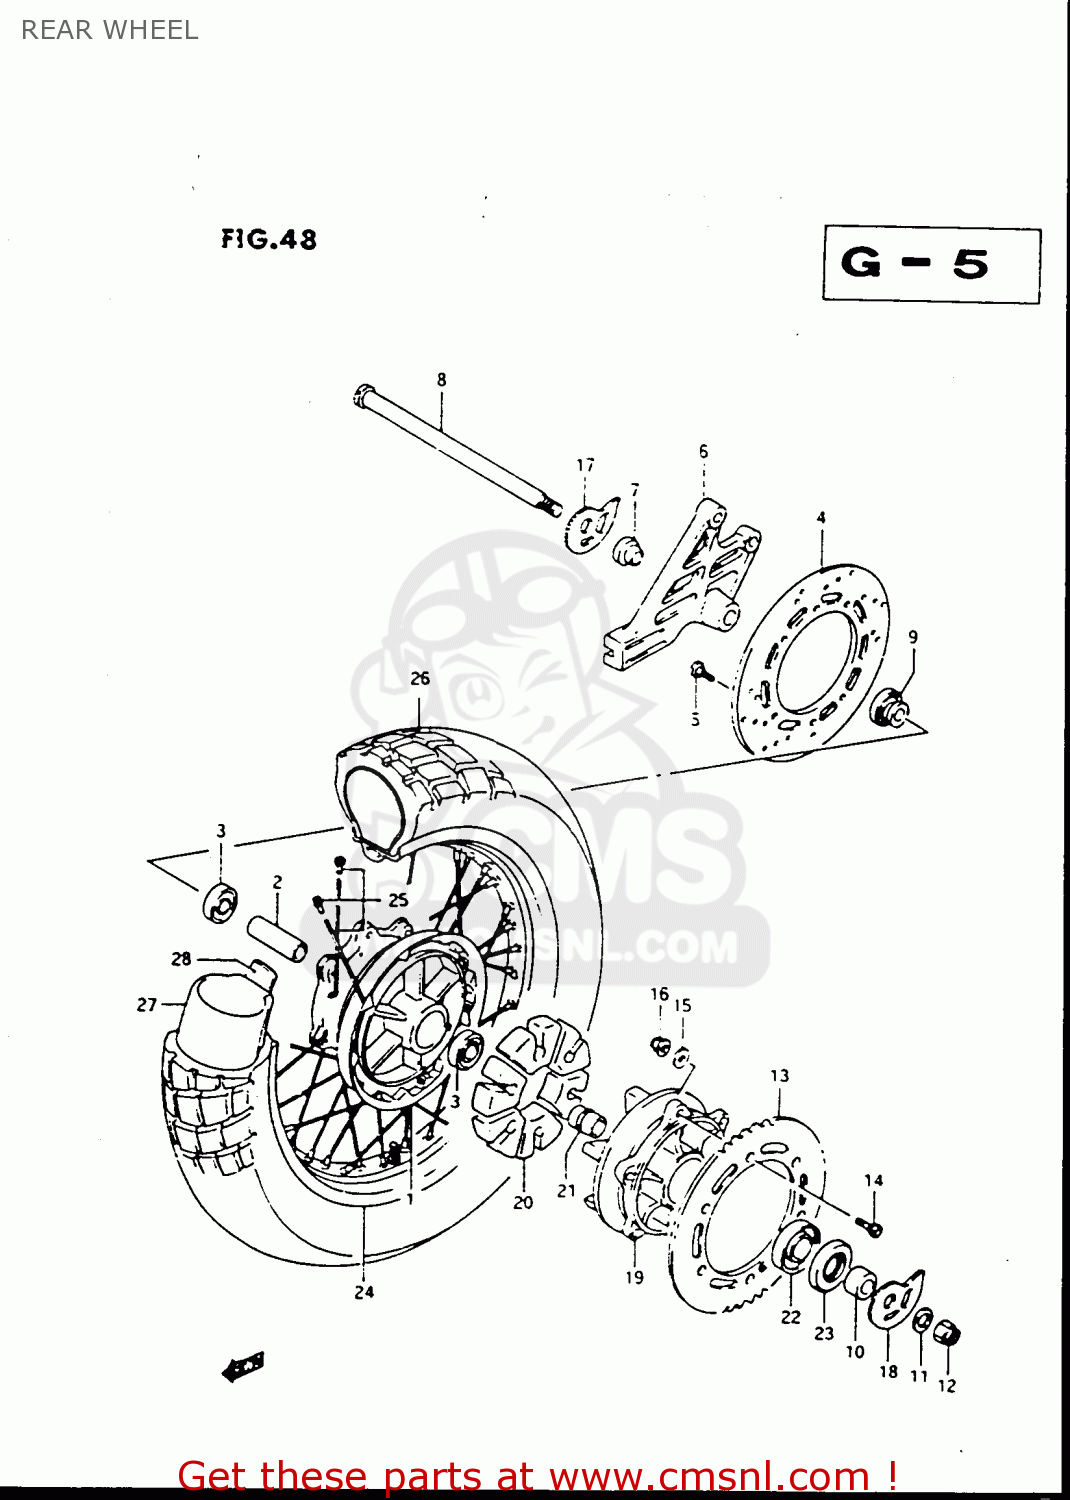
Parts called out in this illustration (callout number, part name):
1	HUB COMP,REAR WHEEL
2	SPACER(17.5X25X78)
3	BEARING
4	DISC,RR BRAKE
5	BOLT,BRAKE DISC
6	BRACKET,RR CALIPER
7	SPACER (17X21X10)
8	AXLE,RR
9	SPACER,RR AXLE,L
10	SPACER(17X33X22.4)
11	WASHER (17X30X3.2)
12	NUT
13	SPROCKET,REAR
14	BOLT(8X30.5)
15	WASHER
16	NUT
17	ADJUSTER,CHAIN
18	PLATE,CHAIN ADJUSTER
19	DRUM,REAR SPROCKET
20	ABSORBER,RR HUB SHOCK
21	RETAINER,RR SPROCKET DRUM
22	BEARING(25X62X17)
23	SEAL,OIL(33X62X7)
24	RIM,REAR WHEEL (17XMT2)
25	SPOKE SET,RR
26	TIRE,REAR (120/90-17 64S)
27	TUBE ASSEMBLY,WHEEL,INNER
28	PROTECTOR
